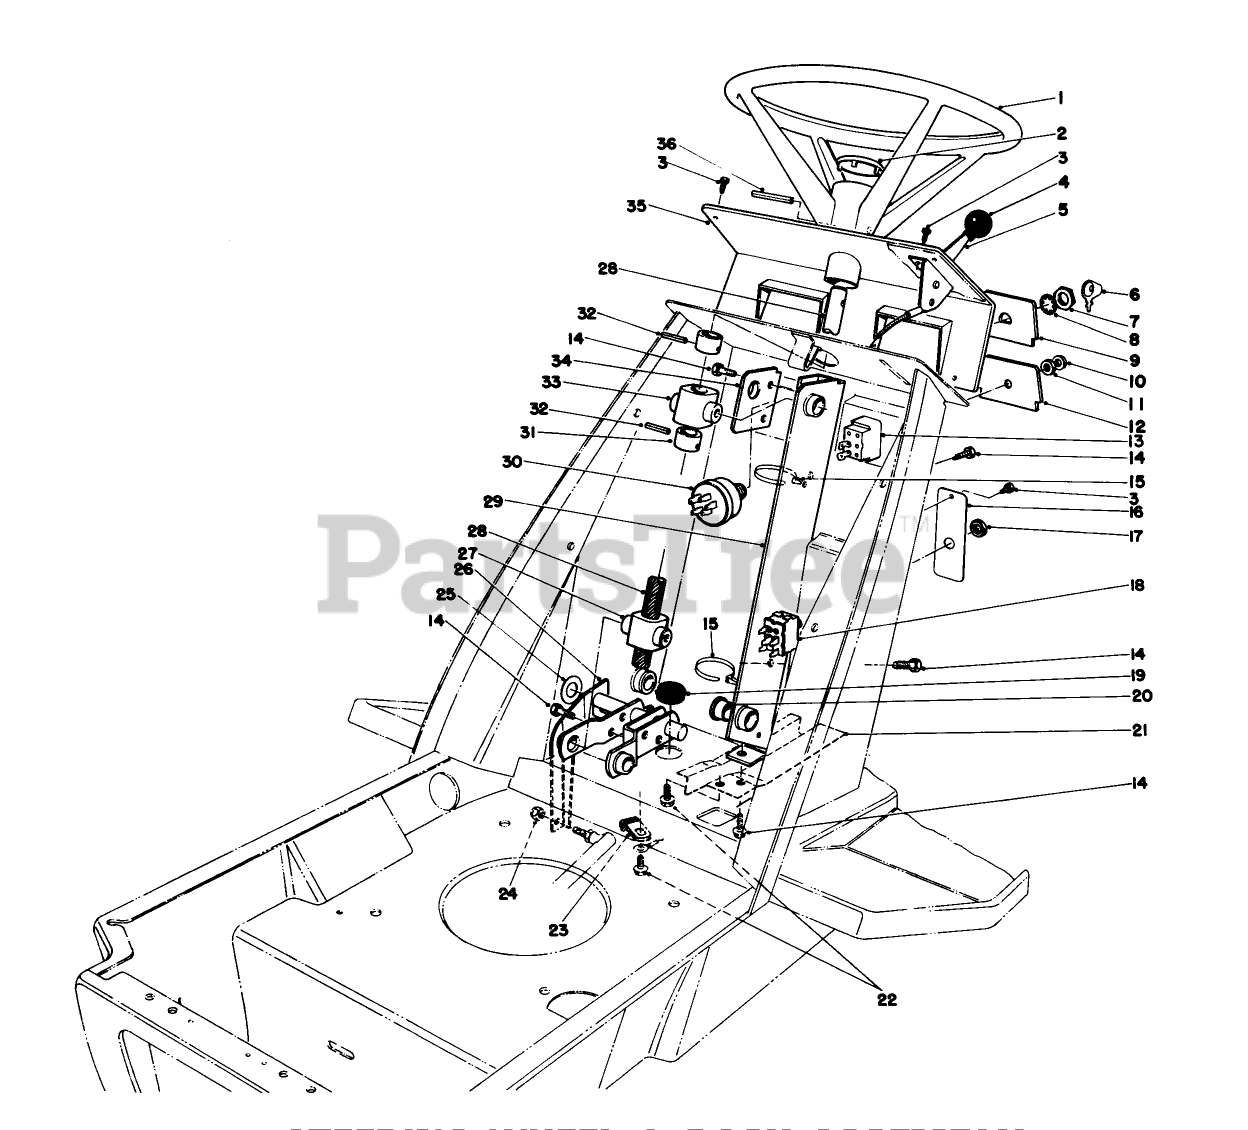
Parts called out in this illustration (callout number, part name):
1	STEERING WHEEL ASM
3	SCREW-HWHTF
4	KNOB-CONTROL
5	Throttle Control (Incl. Ref. #4)
8	WASHER-LOCK
10	Facenut
11	Locknut
13	SWITCH-LIGHT
14	SCREW-THD ROLL, HWH
15	TIE-CABLE
19	GROMMET
20	BEARING-FLANGE
22	SCREW-HWH
23	CLIP-FUEL LINE
24	NUT-HEX
28	STEERING SHAFT
30	SWITCH-STARTER
31	STRG SHAFT COLLAR
32	PIN-SPRING
36	PIN-ROLL
